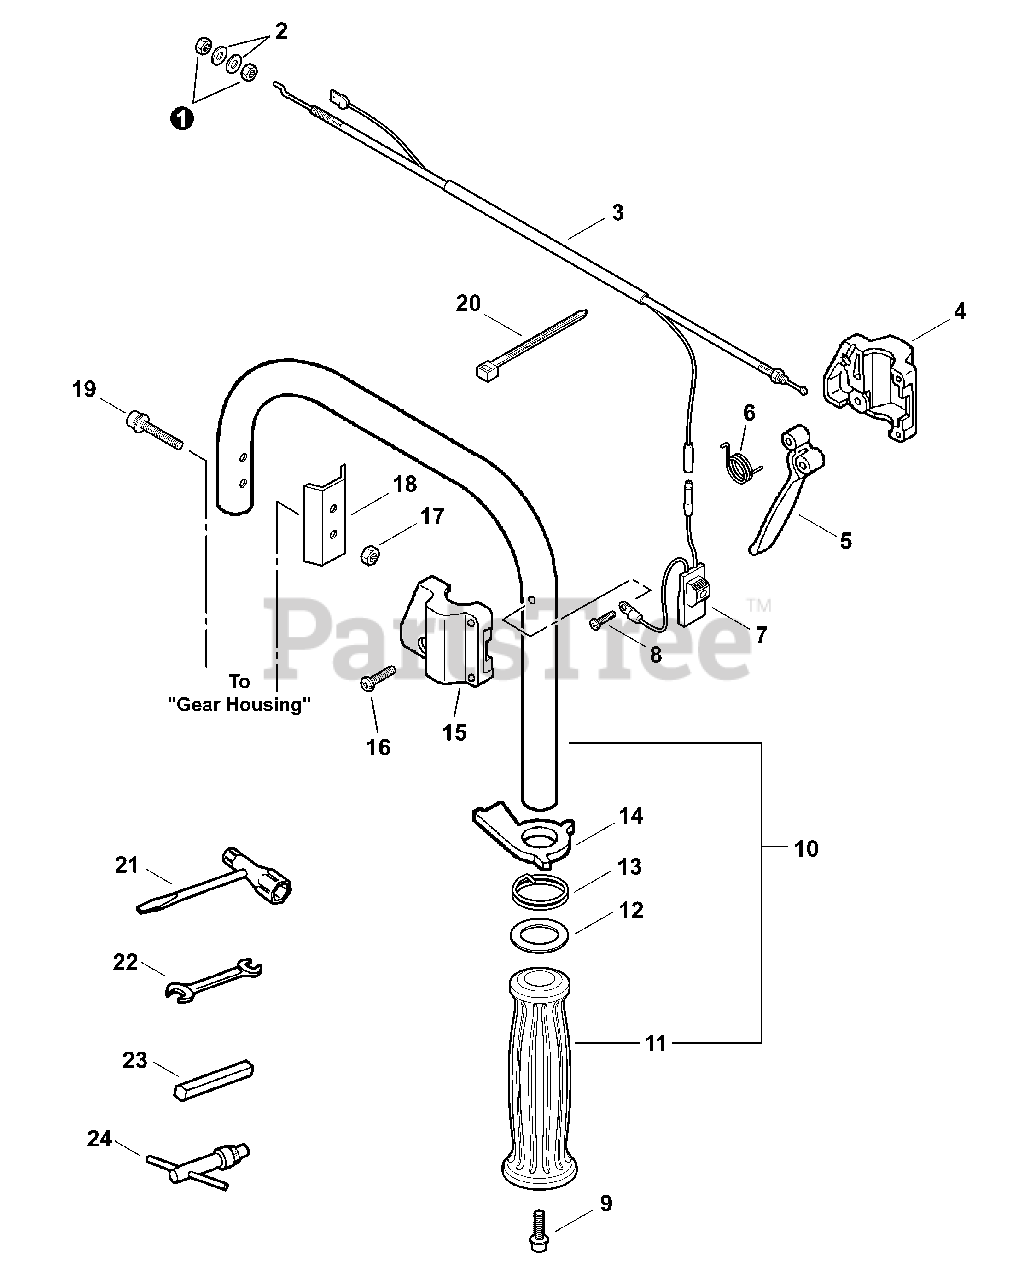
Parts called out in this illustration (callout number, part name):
2	WASHER - 6
3	CONTROL CABLE ASSY
4	BRACKET, THROTTLE CONTROL - RIGHT
5	TRIGGER, THROTTLE
6	SPRING, TRIGGER
7	IGNITION SWITCH ASSY
8	SCREW - 4×30
9	SCREW - 5×16
10	HANDLE ASSY - REAR
11	GRIP, HANDLE - RIGHT
13	SPRING, LOCKOUT LEVER
14	LEVER, TRIGGER LOCKOUT
15	BRACKET, THROTTLE CONTROL - LEFT
16	SCREW - 4×25
17	LOCKNUT - 5
18	PLATE, HANDLE
19	SCREW - 5×35
20	TIE, CABLE
21	T-WRENCH 10×19MM
22	OPEN END WRENCH 17×19 MM
23	HEX BAR 10MM
24	CHUCK KEY
